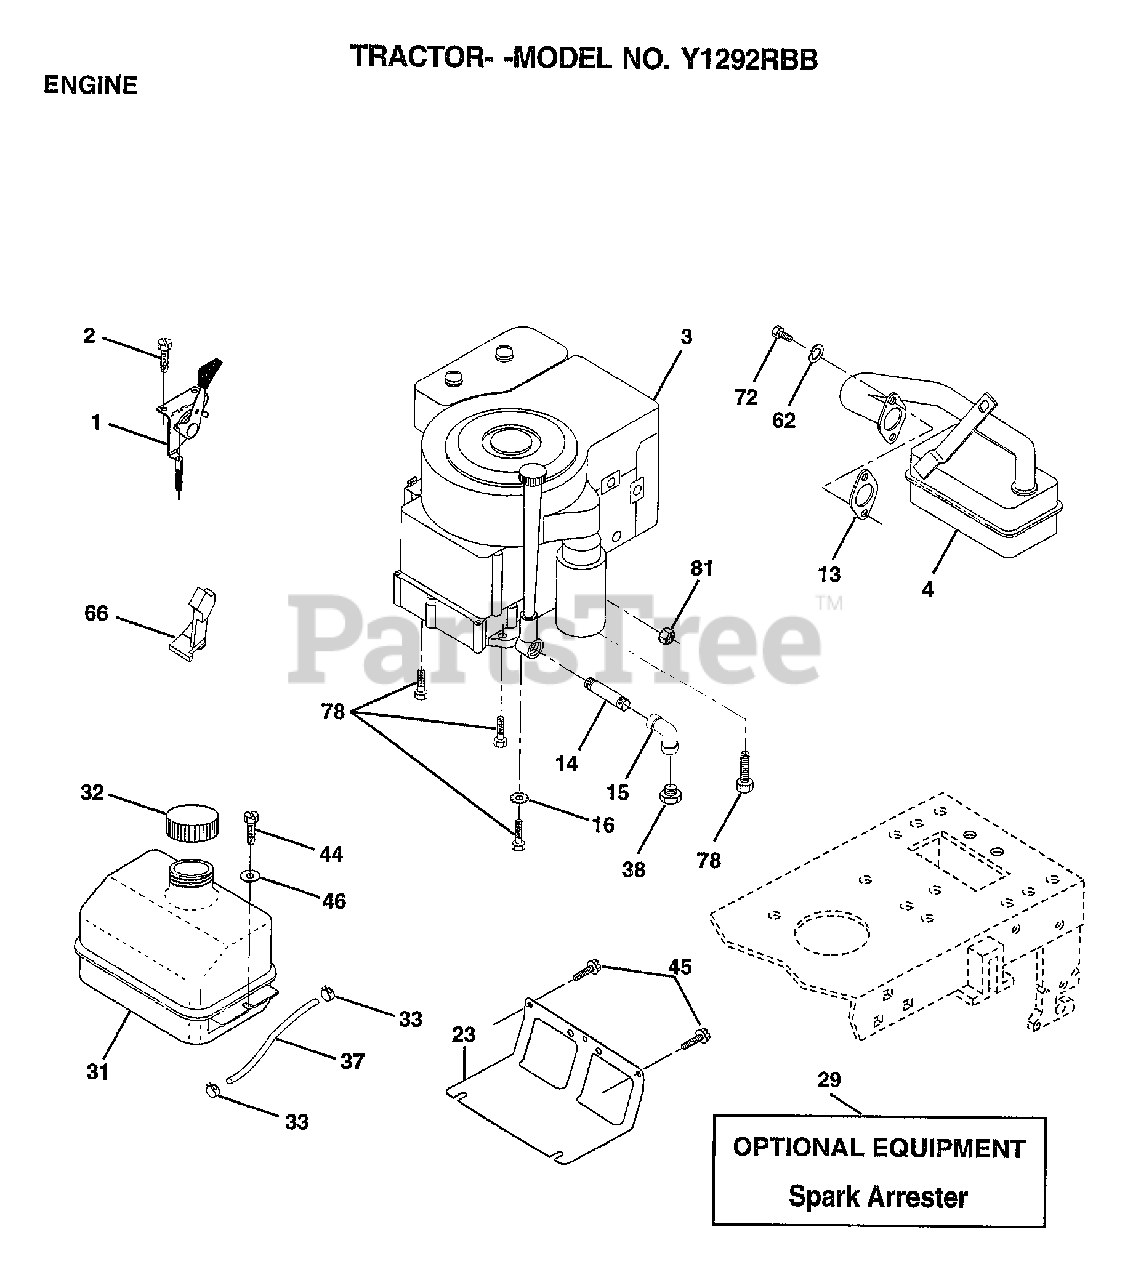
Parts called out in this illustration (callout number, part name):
1	CONTROL.THTL.23.5
2	SCREW LT
4	MUFFLER
14	PIPE NIPPLE
15	ELBOW
16	LOCKWASHER
23	SHIELD BROWNING
31	TANK.FUEL.LT.
32	CAP ASM FUEL
33	HOSE CLAMP
37	LINE FUEL
44	SCREW
45	SCREW
46	WASHER
62	LOCKWASHER
66	"STOP,DASH THROTT"
72	SCREW
78	SCREW
81	NUT
